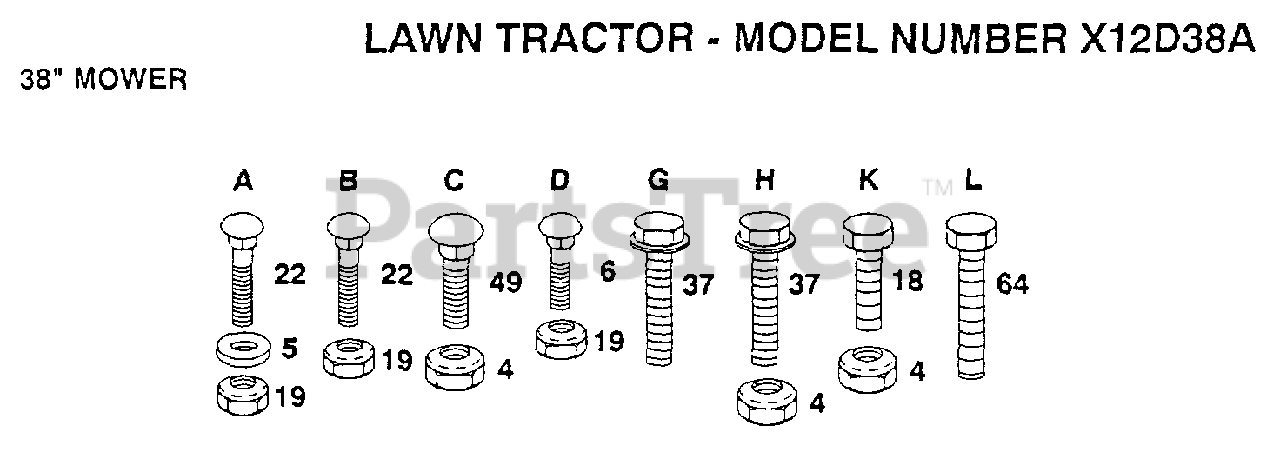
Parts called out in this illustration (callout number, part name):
5	WASHER M
6	BOLT
22	BOLT
37	SCREW
49	BOLT
64	BOLT.3/8-14X1.25
